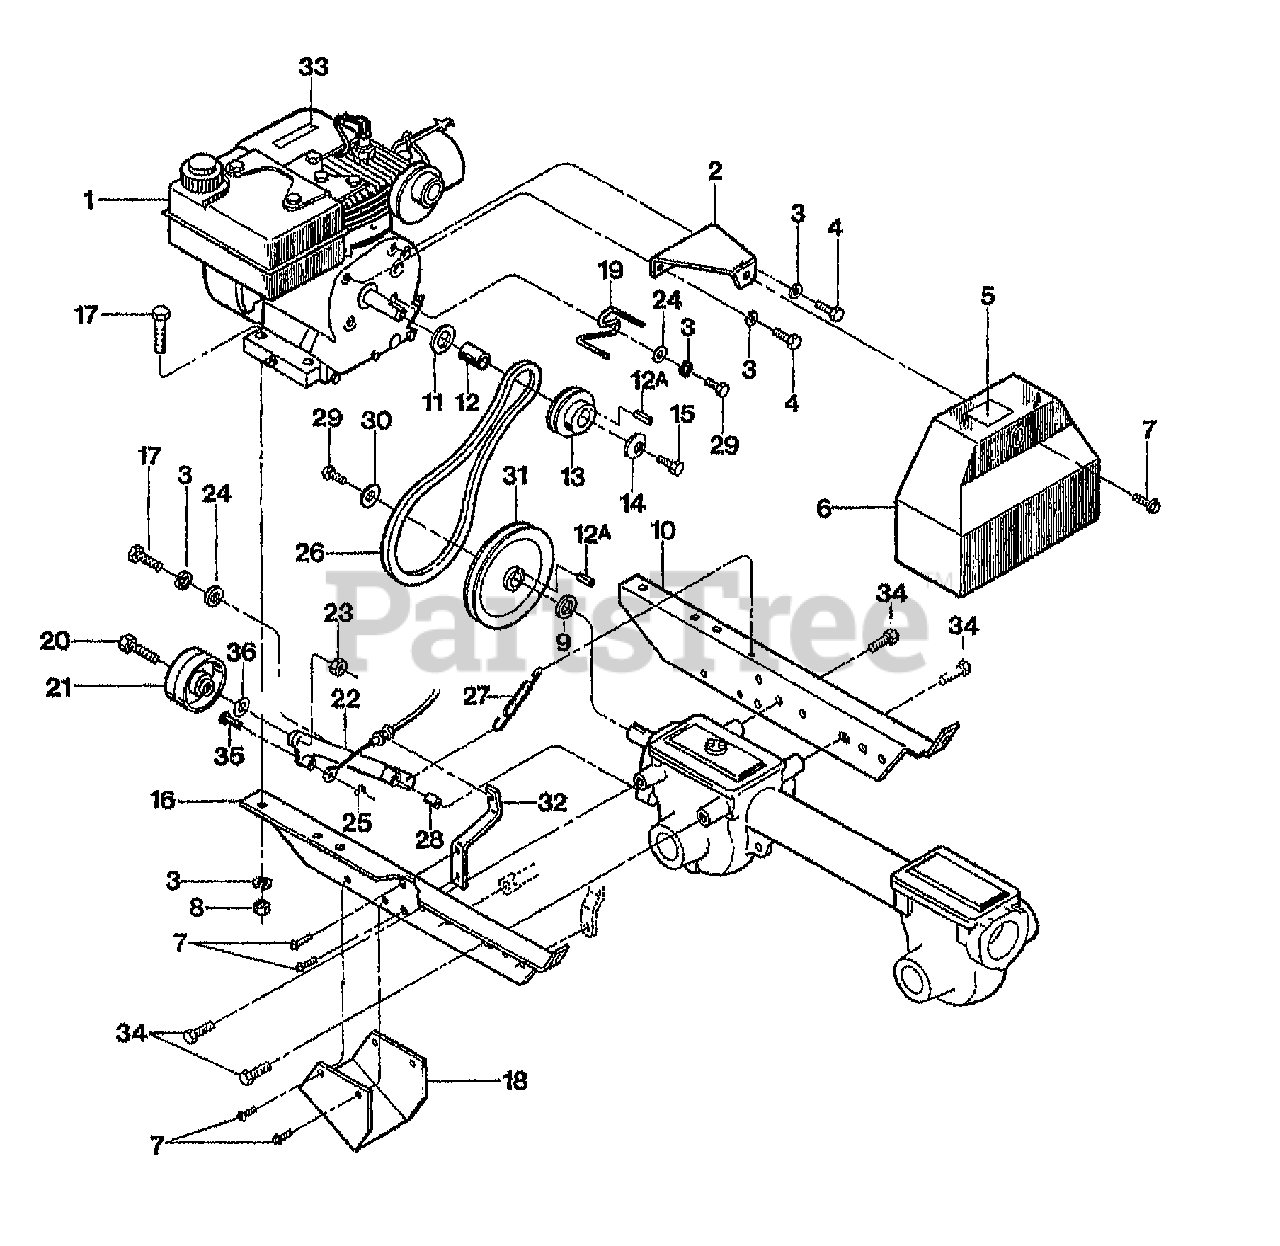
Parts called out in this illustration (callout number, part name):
1	ENGINE, TECUMSEH 3HP (H30-35387S)
2	BRKT-BELT COVER PNT
3	WASHER-LK .312 ZP
4	SCR-HH 5/16-24X.50
5	DECAL-HOT SURFACE
6	COVER-BELT W/DECAL 55053
7	SCR-HWH 1/4-20 X .5 STH
8	NUT-HEX 5/16-18 ZP
9	WASHER-SHLDR HARDENED
10	BRKT-ENGINE PNT
11	SHIM-1.0X.7656X.031
12	SPACER
12A	KEY-.188 SQX1.0
13	PULLEY-ENGINE
14	WASHER-.994X.413X.145
15	SCR-HH 3/8-24X1.0 G5 ZP
16	BRKT-ENGINE LEFT PNT
17	SCR-HH 5/16-18X1.5 G5 ZP
18	GUARD-BELT/PULLEY PNT
19	BELT STOP
20	BOLT-HH 3/8-16X1.5 FTH ZP
21	PULLEY-IDLER FORWARD
22	ARM-IDLER PNT
23	NUT-H/LK 3/8-16
24	WASHER-FLAT 5/16 SAE
25	RING-KLIP .188 DIA
26	BELT-V TUFFY
27	SPRING-RETURN
28	BUSHING-IDLER LEVER PM
29	SCR-HH 5/16-24X.75 G5 ZP
30	WASHER-.827X.331X.098
31	PULLEY-TRANSMISSION
32	BRKT-CABLE MTG PNT
33	DECAL-STARTING STABIL
34	SCR-HFLK 5/16-18X.62 G5ZP
35	PIN-CLEVIS CABLE
36	WASHER-FLAT 3/8 SAE
